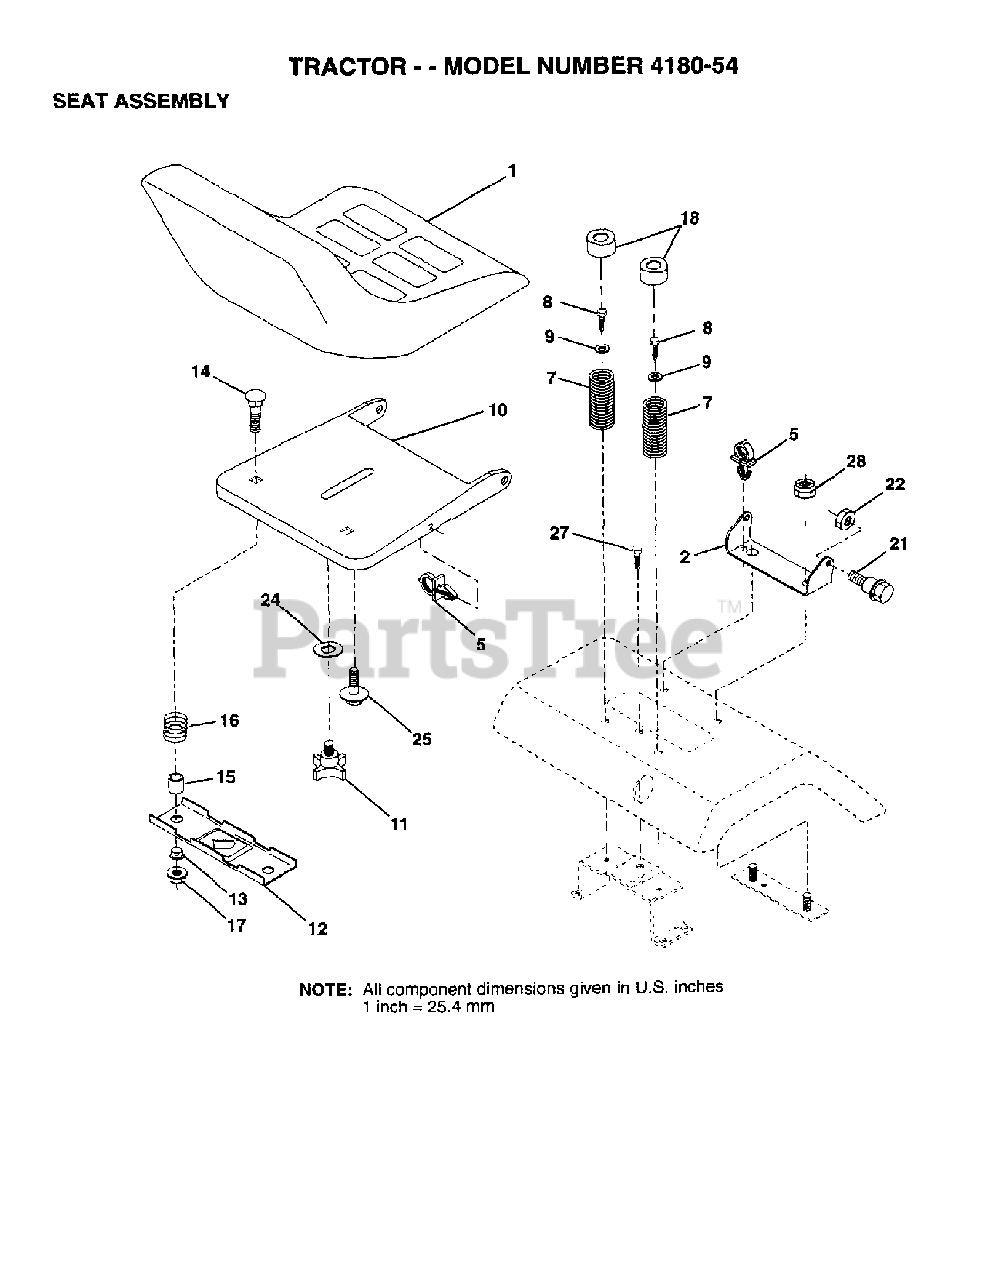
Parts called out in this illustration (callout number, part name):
2	BRKT,SEAT PIVOT**
5	PUSH CLIP
7	SPRING COMPRESSION
8	SCREW LT
10	PAN SEAT
12	BRKT SWITCH
14	BOLT CARRIAGE 1/4-20X1 3/8
15	SPACER SPLIT
16	SPRING COMPRESSED
17	NUT T
18	CAP SPRING
21	BOLT, SHOULDER LT
22	LOCKNUT
25	BOLT, SHOULDER**
26	LOCKNUT
27	SCREW LT
